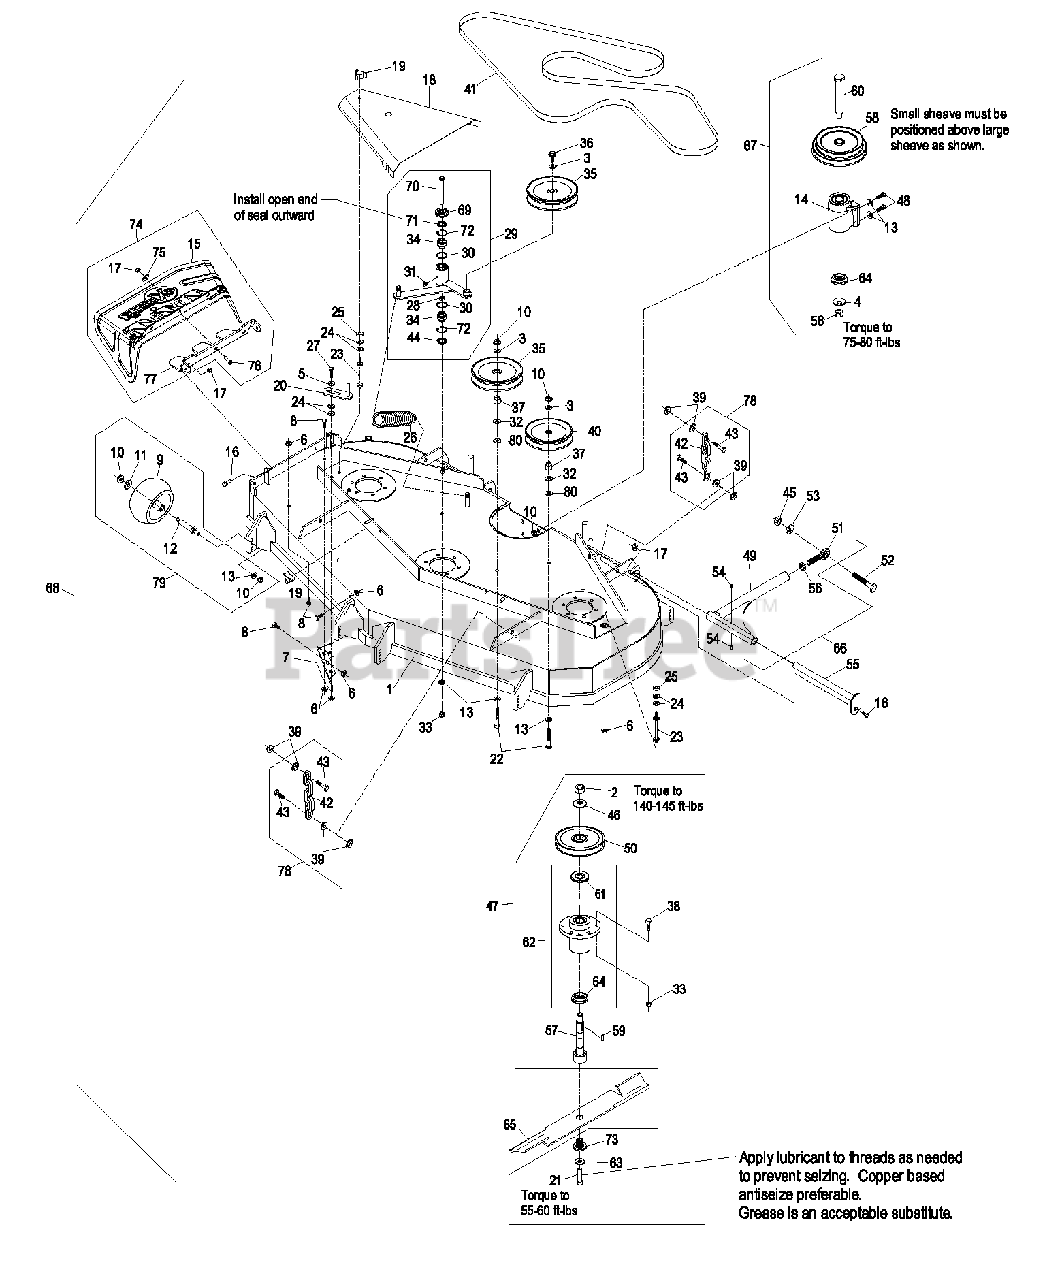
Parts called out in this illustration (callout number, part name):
1	ASM,DECK W/DECALS LZ604
2	NUT-HH
3	WASHER-FLAT
4	WASHER-SPRING
5	WASHER-SPRING
7	WLD,BAFFLE DISCHARGE
8	SCREW-HH
9	ROLLER-SCALP, ANTI
10	NUT-HHF, WHIZ
13	WASHER-BELLEVILLE
14	KIT, JACKSHAFT ASSY
15	CHUTE,DISCHARGE
16	SCREW-HH
17	NUT-LOCK, NI
18	SHIELD,BELT
19	KNOB-3 PRONG
20	GUIDE-BELT
21	SCREW-HH
22	BOLT-CARR
23	STUD-SHIELD, BELT (SHORT)
24	WASHER-FLAT
27	SCREW-HH
29	KIT,DECK IDLER LZ/XP
31	FITTING-GREASE, 90 DEG
32	WASHER-FLAT
33	NUT-LOCK, NI
34	BEARING-SPHERICAL
36	SCREW-HHF
37	BUSHING-IDLER
38	SCREW-HH
40	PULLEY-IDLER
41	BELT,BLADE DRIVE
42	CHAIN-LIFT, DECK
43	SCREW-HH
44	SEAL-LIP, DOUBLE
45	NUT-HEX
47	ASM, CUTTER HSG COMPLETE
48	SCREW-HH
49	STRUT-DECK
50	SHEAVE,BLADE DRIVE 6.30
51	BALLJOINT-SPHERICAL
52	SCREW-HH
53	WASHER-LOCK
54	FITTING-GREASE
55	PIN-STRUT
56	NUT-HEX
57	KIT, SPLINED SPINDLE 103-
58	SHEAVE, JACKSHAFT DOUBLE
60	JACKSHAFT
61	GUARD-BEARING, TOP
62	KIT, CUTTER HOUSING
63	WASHER-SPRING
64	SPACER-GUARD, BOTTOM
66	STRUT ASM
67	KIT,JACKSHAFT 60/72-3750
68	Complete Deck Assy
69	GUARD-TOP
70	SCREW-HH
71	SEAL-LIP, SINGLE
72	RING-SNAP
73	BUSHING,SPLINED
75	WASHER-FLAT
76	SCREW-CARR
77	BRACKET,DISCHARGE CHUTE
78	DECK CHAIN ASM
